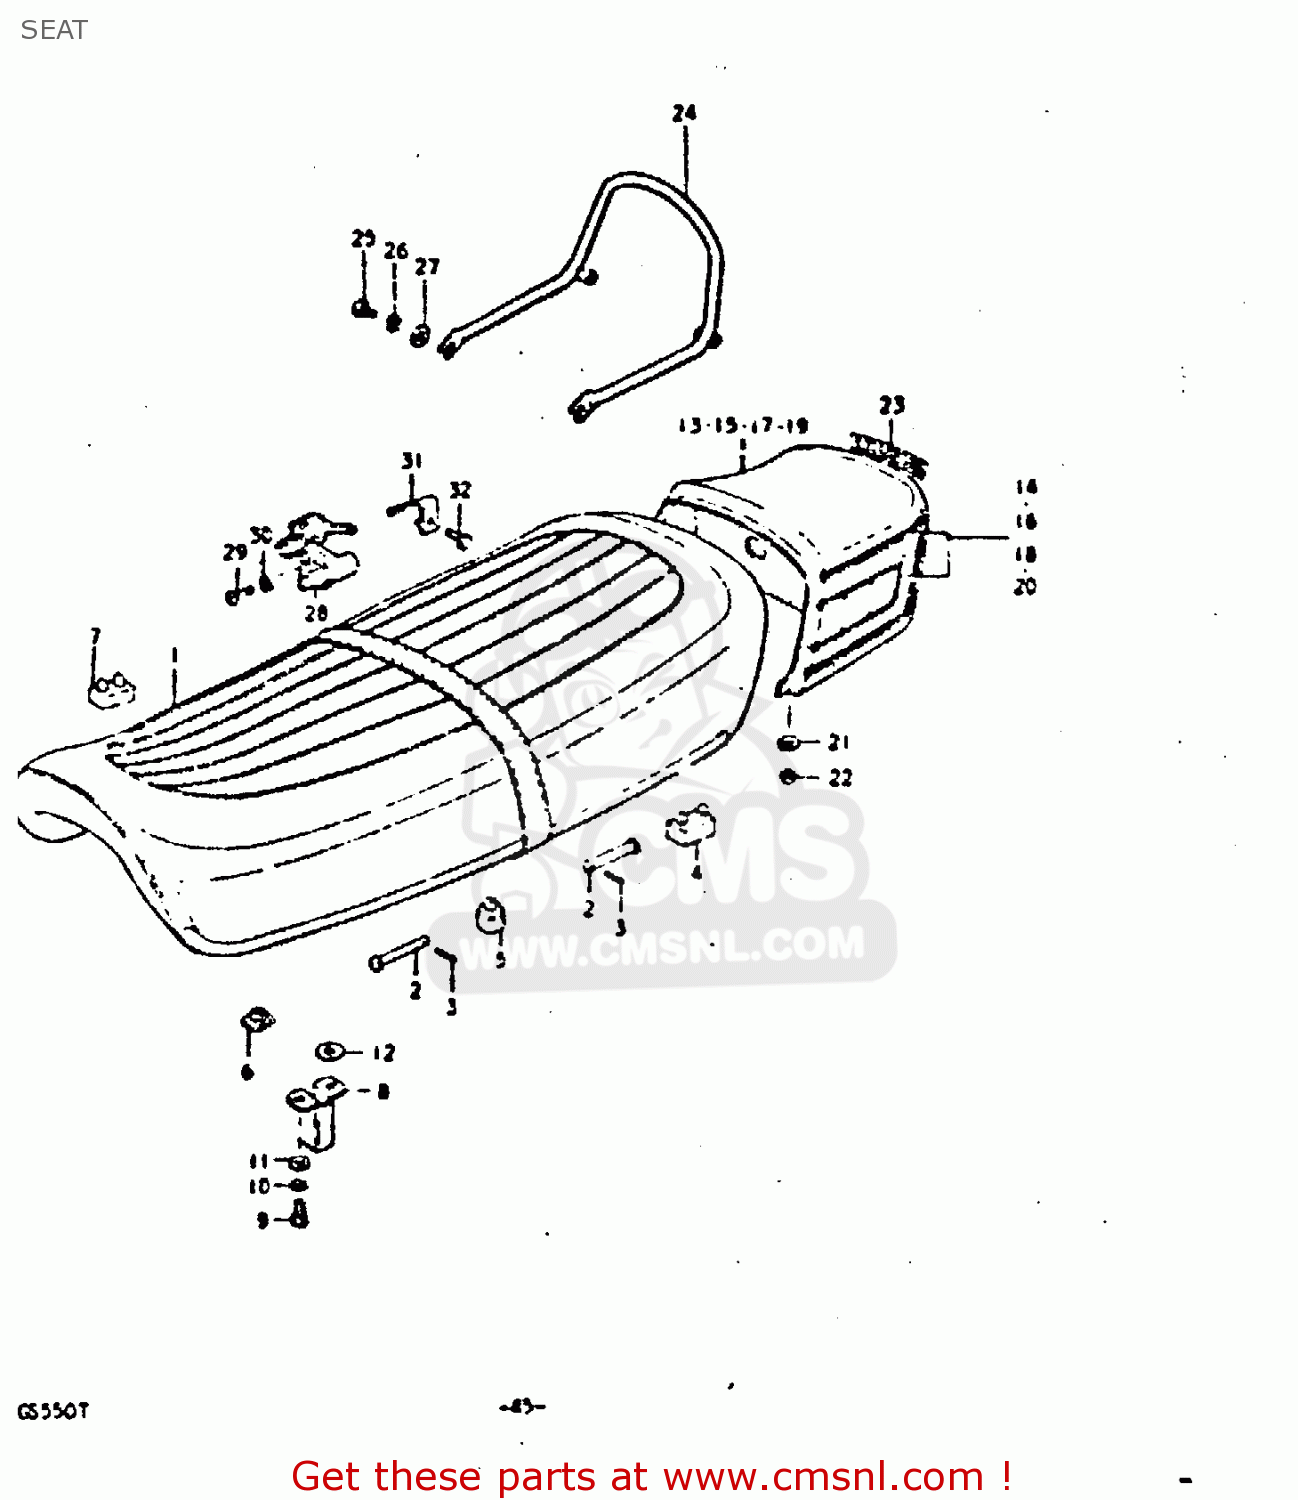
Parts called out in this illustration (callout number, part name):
1	SEAT ASSEMBLY
2	PIN
3	PIN
4	CUSHION
5	CUSHION(11.5X22X20)
6	CUSHION
7	CUSHION
8	STRIKER,SEAT LOCK
9	BOLT
10	LOCK WASHER
11	WASHER 6MM
12	WASHER(8.5X18X1)
13	COVER,SEAT TAIL
14	TAPE SET
15	COVER, SEAT TAIL
16	TAPE SET
17	COVER,SEAT TAIL
18	TAPE SET
21	WASHER
22	NUT 6MM
23	EMBLEM
24	HANDLE, PILLION RIDER
25	BOLT
26	LOCK WASHER
27	WASHER
28	LOCK ASSY,SEAT
29	SCREW
30	LOCK WASHER
31	SPRING,HELMET HOLDER
32	BOLT 5X16
